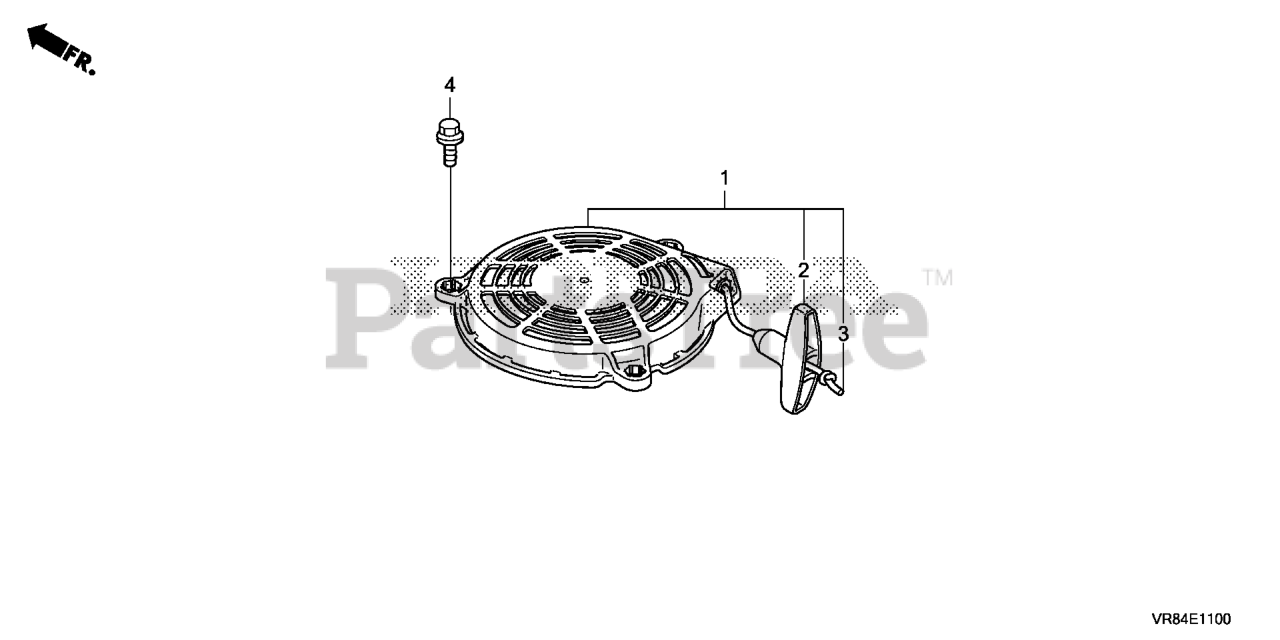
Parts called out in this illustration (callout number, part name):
1	STARTER ASSY., RECOIL (LONG ROPE)
2	KNOB, RECOIL STARTER
3	ROPE, RECOIL STARTER (LONG TYPE)
4	BOLT, FLANGE (6X14)
